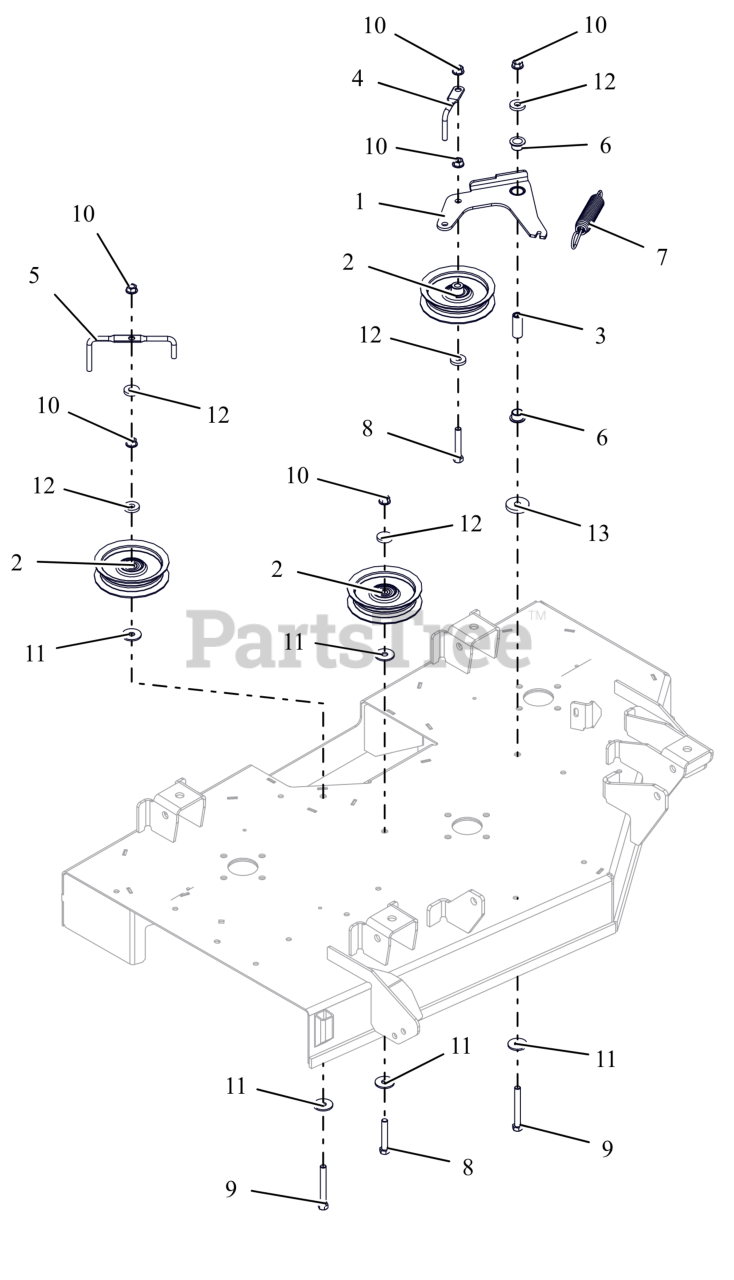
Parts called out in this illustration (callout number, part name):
1	WLDMT, IDLER ARM-42"
2	IDLER, FLAT - 4.06" X .75"
3	SPACER, .375IDX.625ODX1.66 PM
4	WIREFORM-BELT FINGER
5	BELT FINGER
6	BSHG-FLG, .625X.750X.500X1.00
7	SG-TENS .135X.98X6.0 WLD 62
8	BLT,HEX .38-16X2.25 G5 ZCC
9	BLT, HEX .38-16X3.00F G5 ZCC
10	NUT-LK-CTR-FLG .375-16 GF ZCC
11	WSHR FL STL .406X1.25X.10ZC120
12	WSHR, FLT .406X1.00X.188 ZCC
13	WSHR, FLT .406X1.50X.245 ZCC
